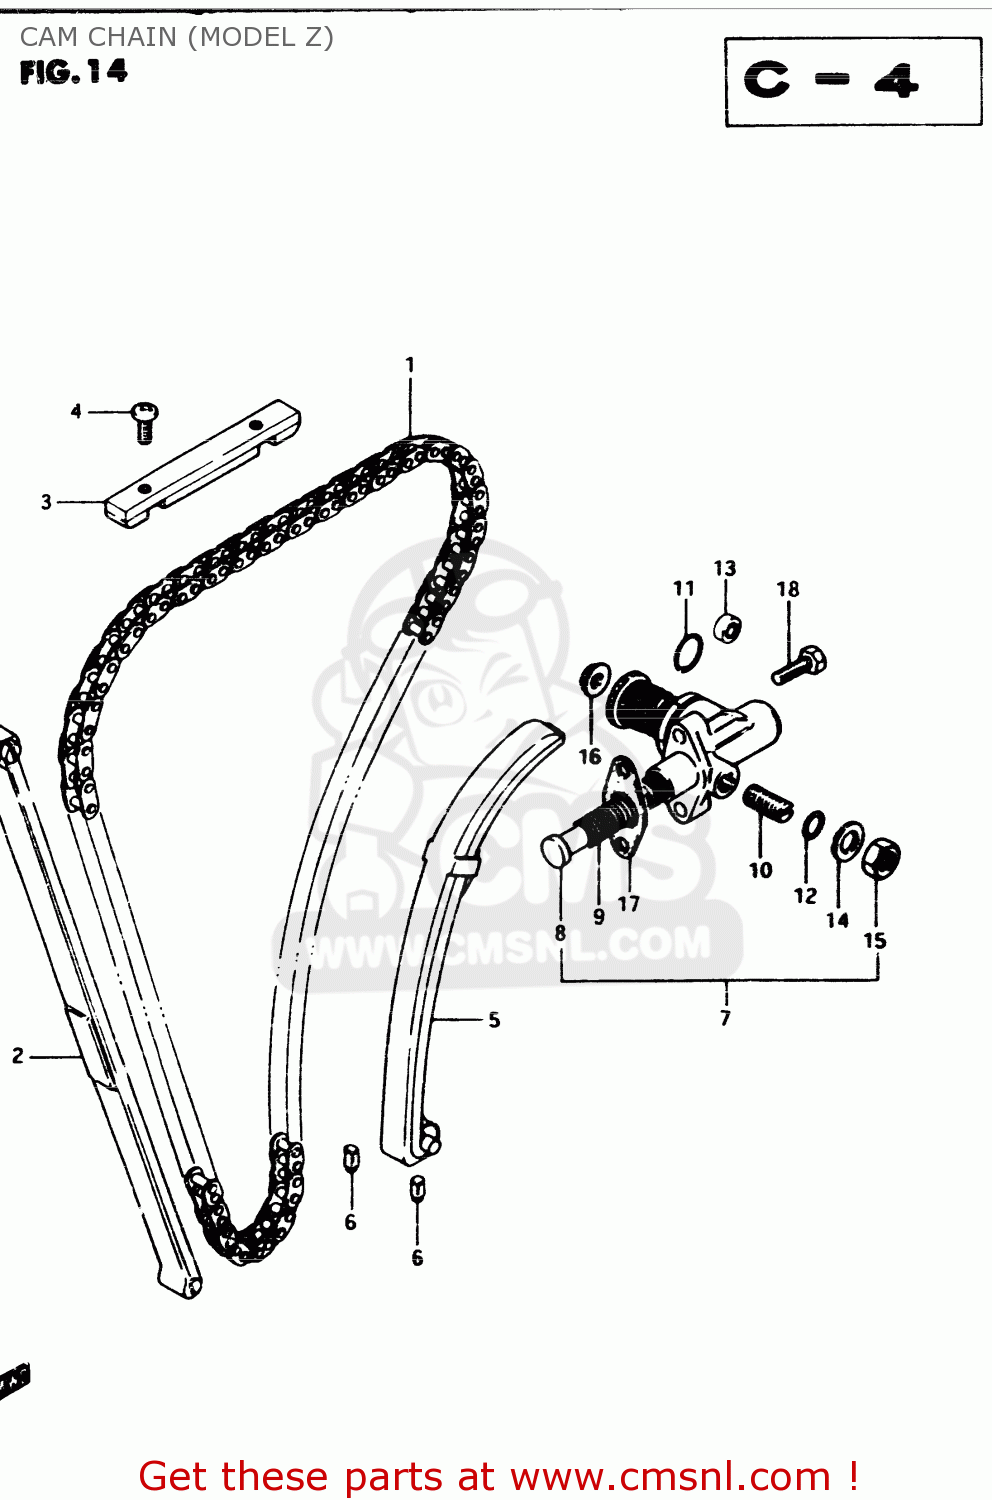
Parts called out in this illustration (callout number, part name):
1	CHAIN,CAMSHAFT DRIVE
2	GUIDE,CAM CHAIN NO.1
3	GUIDE,CAM CHAIN NO.3
4	SCREW
5	TENSIONER,CAM CHAIN
6	CUSHION,CAM CHAIN TENSIONER
7	ADJUSTER,CAM CHAIN TENSIONER
8	ROD,PUSH
9	SPRING
10	SCREW
11	O RING(D:2.4,ID:20.8)
12	O RING(D:1.9,ID:5.7)
13	SEAL,OIL(10X16X4)
14	WASHER
15	NUT
16	NUT
17	GASKET,TENSIONER ADJUSTER (MCA)
18	SCREW (6X25)
